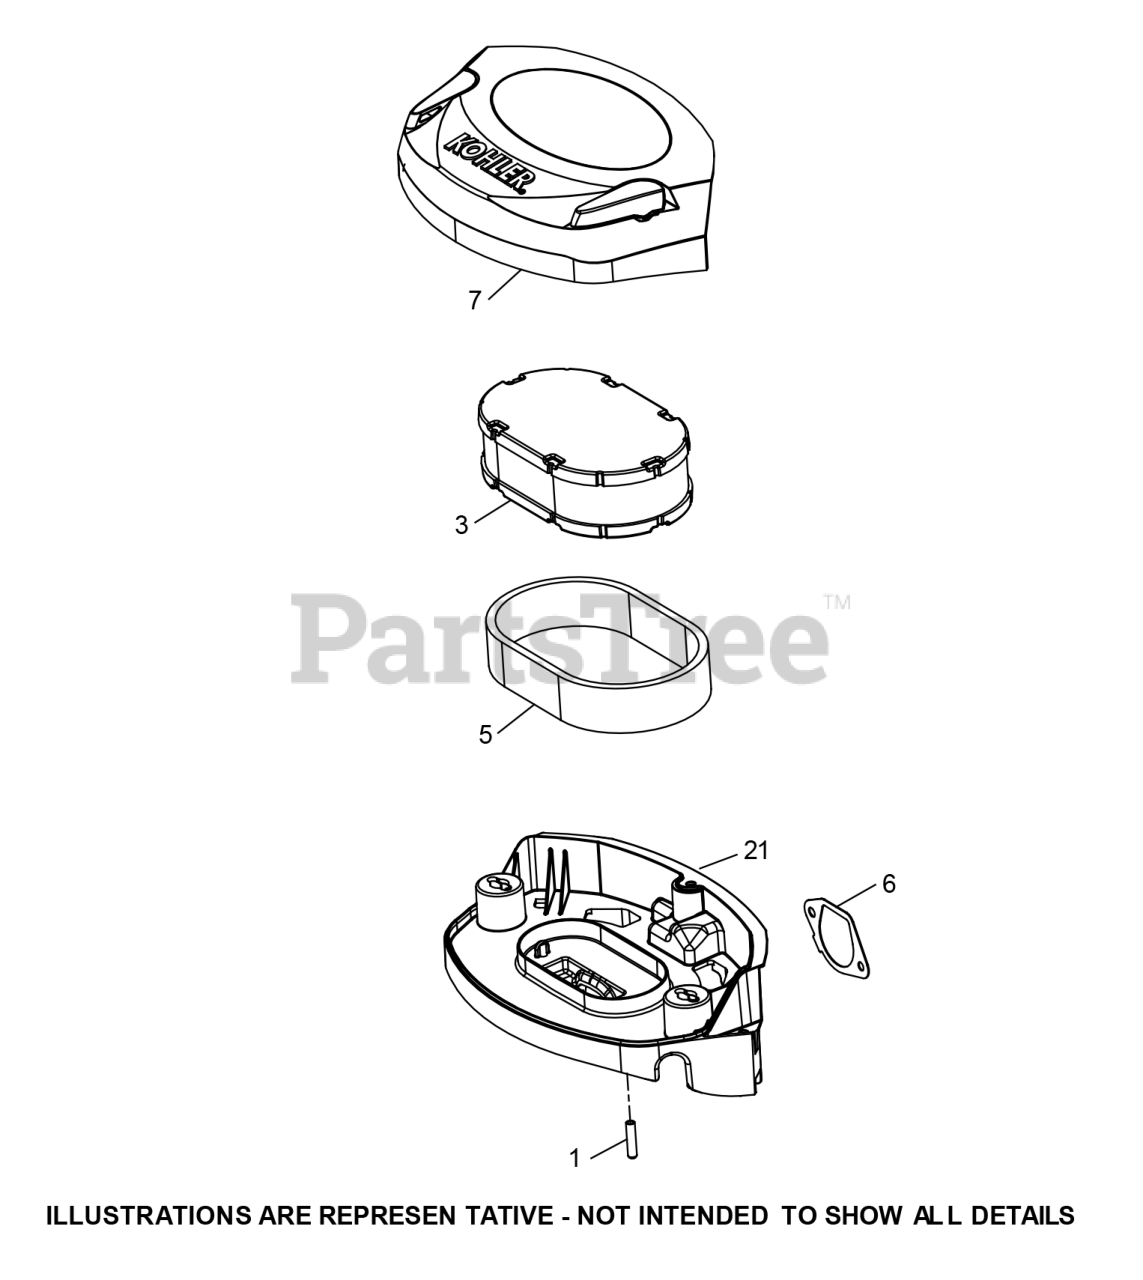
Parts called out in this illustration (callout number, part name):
3	FLTR KIT-AIR/PRECL
5	PRECLNR-FOAM (LPAC
6	GASKET-AIR CLNR BA
7	AIR CLEANER COVER ASSEMBLY
21	AIR CLEANER BASE ASSEMBLY
